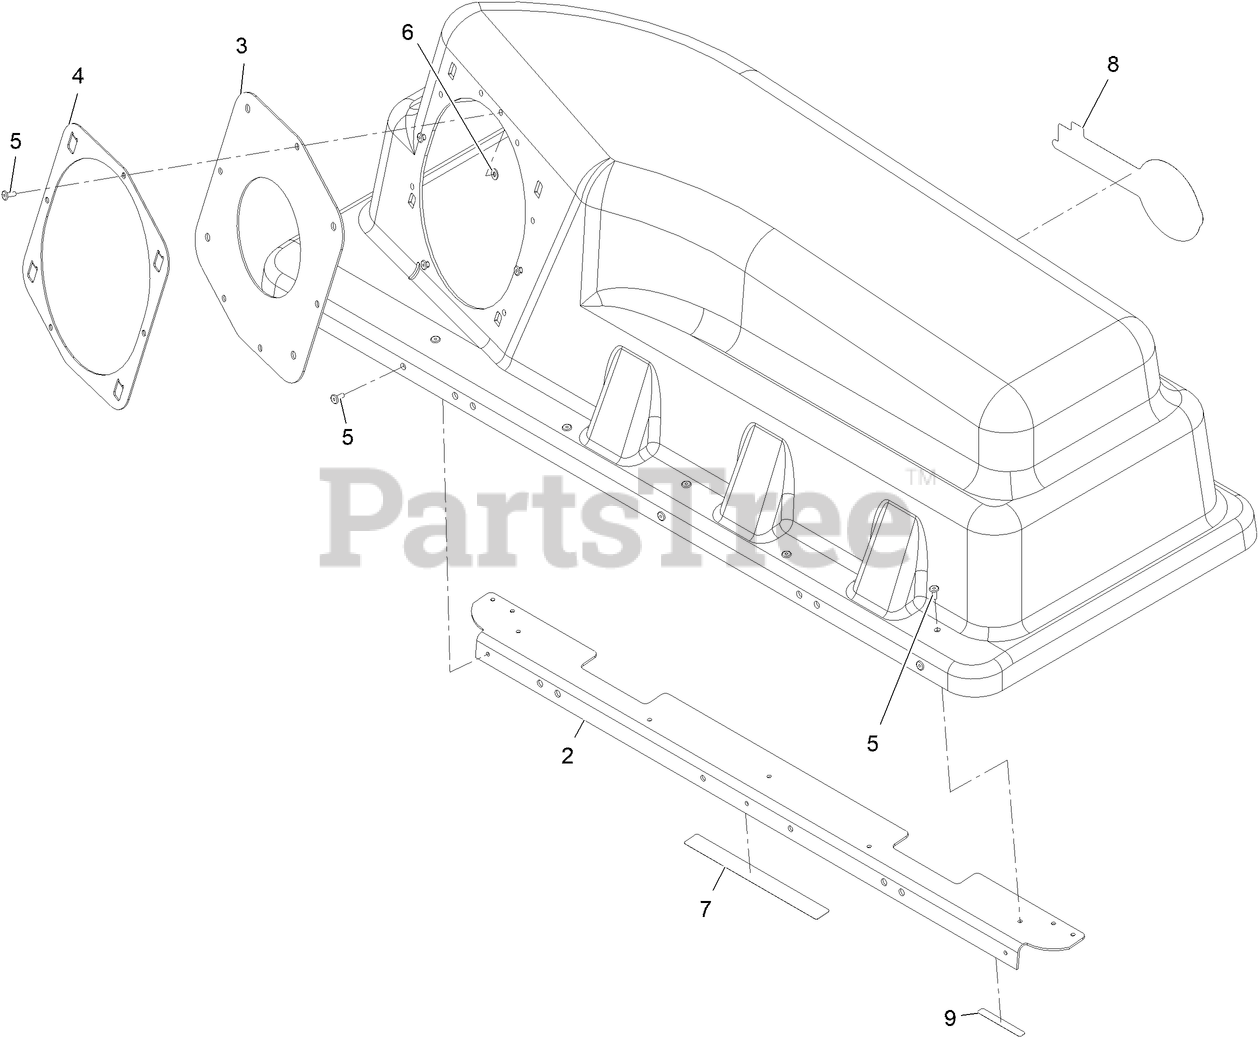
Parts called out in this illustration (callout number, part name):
2	STIFFENER-BAGGER, TOP
4	RING-RETAINER
5	RIVET-BLIND
6	WASHER-FLAT
7	DECAL-CRUSH HAZARD BAGGER
8	DECAL-EXMARK LOGO
9	DECAL-WARNING
